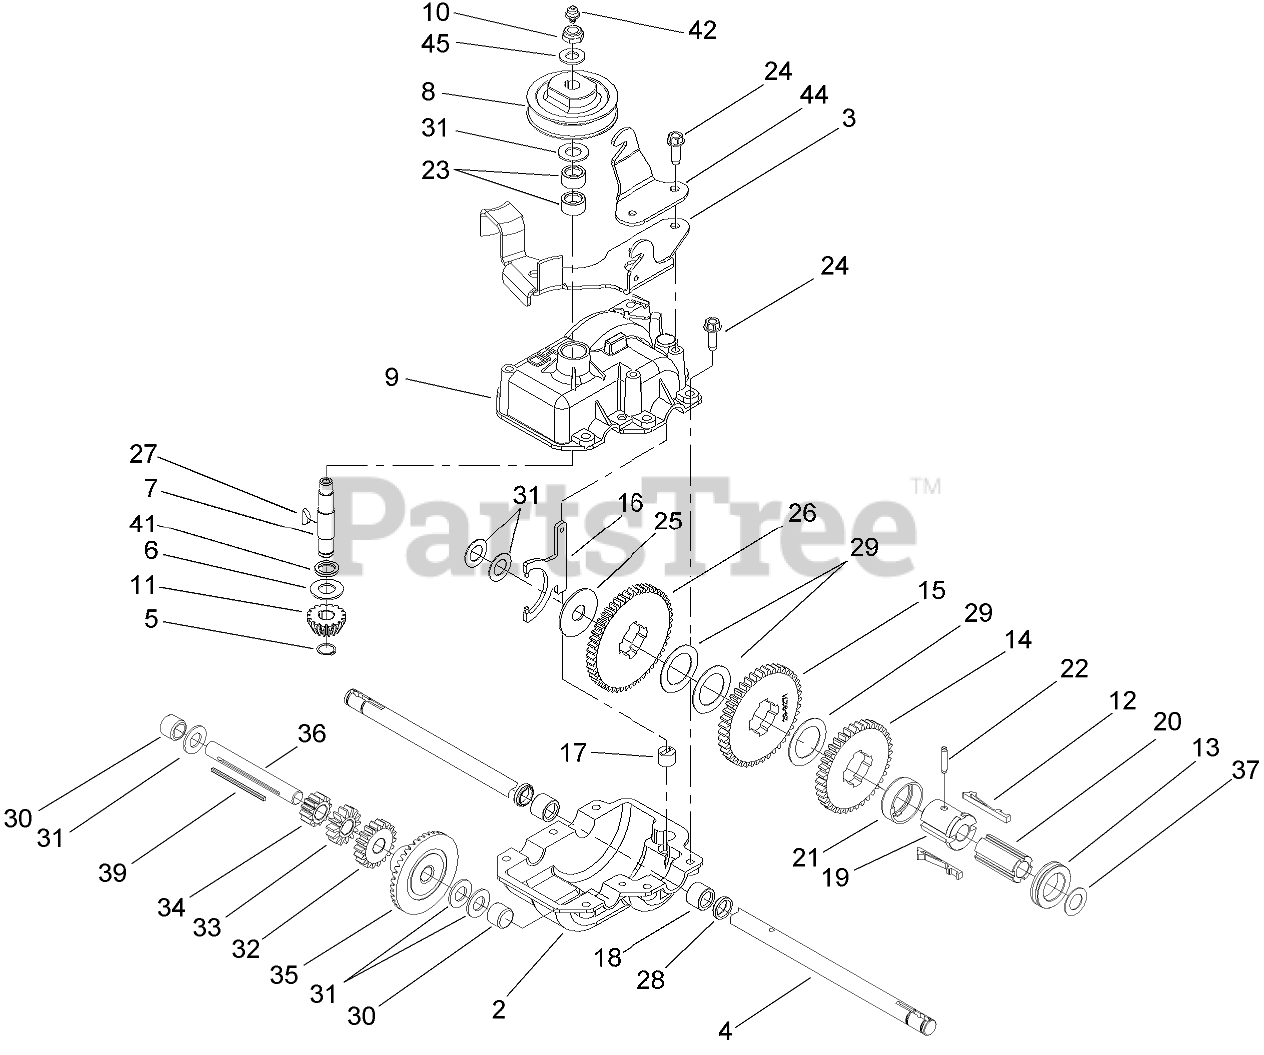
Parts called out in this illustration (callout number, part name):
2	CASE-GEAR, LOWER
3	BRACKET-GUIDE, BELT
4	SHAFT-OUTPUT
5	RING-RETAINING
6	WASHER-THRUST
7	INPUT SHAFT ASM
8	PULLEY
9	UPPER GEARCASE ASM
10	NUT-HEX
11	PINION-BEVEL
12	KEY-SHIFT
13	COLLAR-SHIFT
14	GEAR-38T
15	GEAR-42T
16	YOKE-SHIFT
17	BUSHING-YOKE
18	SEAL-OIL
19	SLEEVE-GEAR
20	SLEEVE
21	RETAINER-KEY
22	PIN-GROOVE
23	BEARING-NEEDLE
24	SCREW-HWHTF
25	WASHER
27	KEY-WOODRUFF
28	BEARING-ROLLER
29	WASHER
30	BEARING-NEEDLE, CLOSED
31	WASHER-THRUST
32	GEAR-18T
33	GEAR-14T
34	GEAR-12T
35	GEAR-BEVEL
36	SHAFT-INTERMEDIATE
37	WASHER-PLAIN
42	FITTING-GREASE, ZERK
44	BRACKET-ENGAGE, TRACTION
45	WASHER-FLAT
